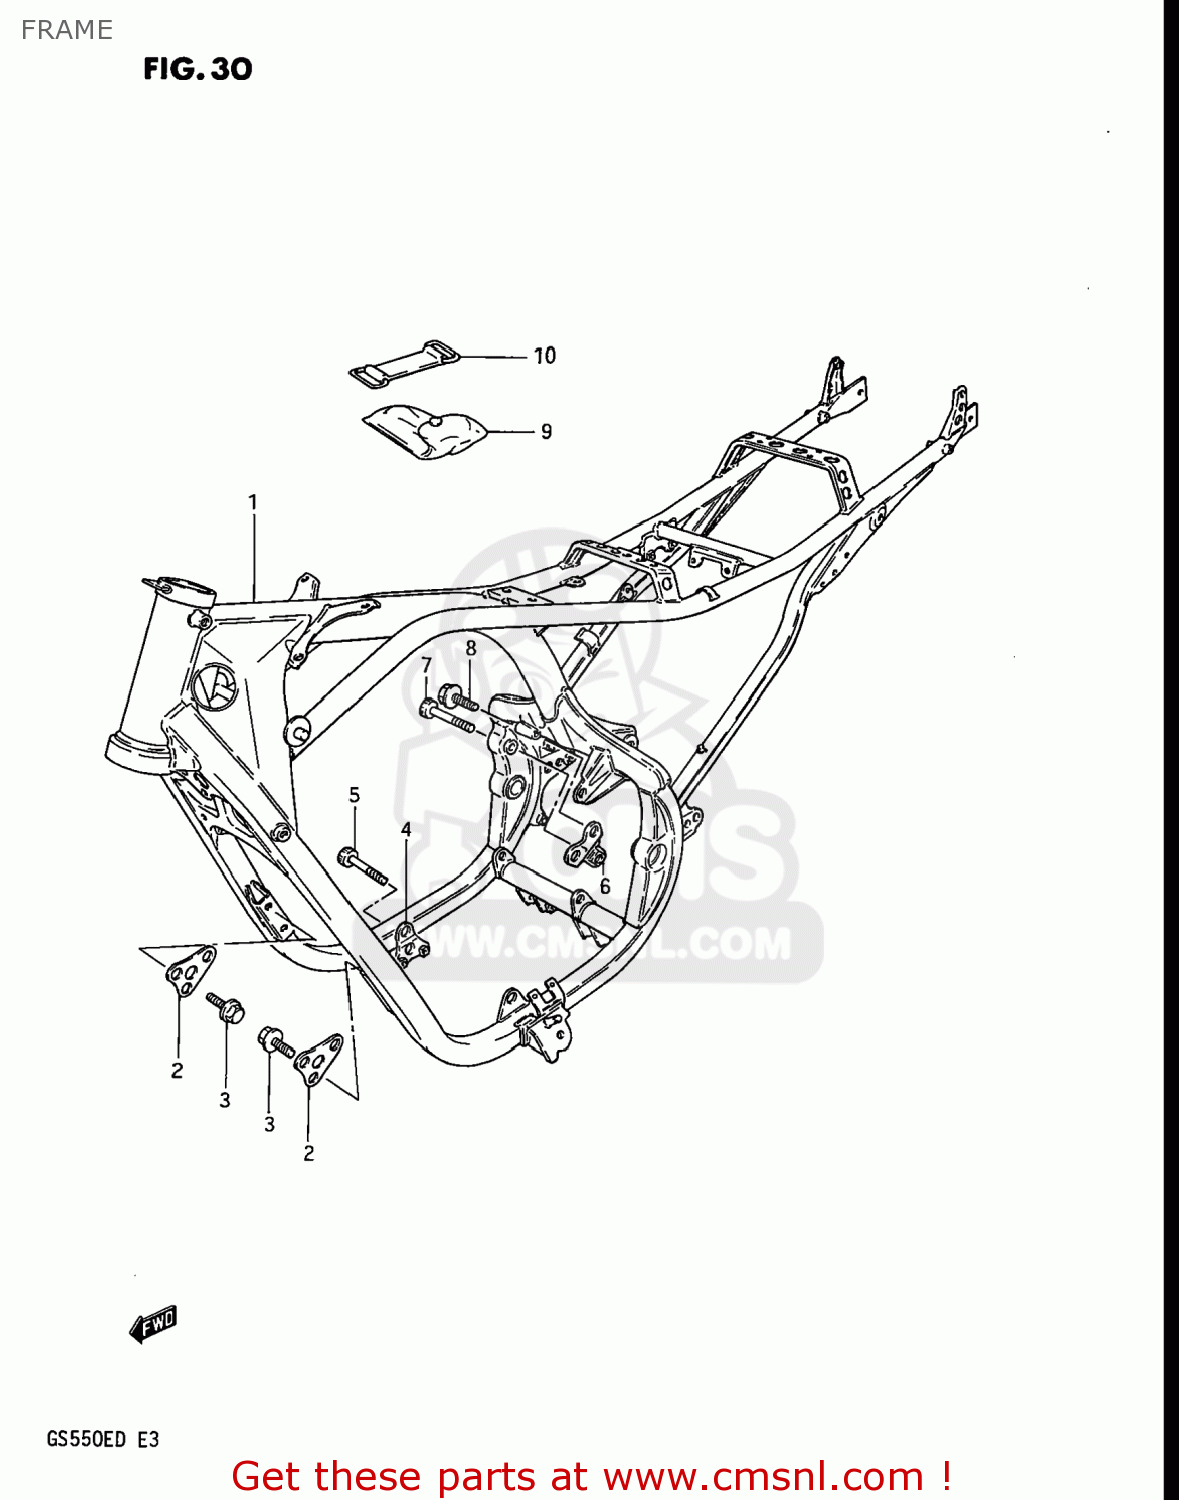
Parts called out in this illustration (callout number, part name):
1	FRAME
2	PLATE,ENGINE MOUNTING
3	BOLT
4	PLATE,ENGINE MOUNTING NO
5	BOLT
6	PLATE,ENGINE MOUNTING NO.4
7	BOLT
8	BOLT
9	TOOL ASSY
10	BAND
